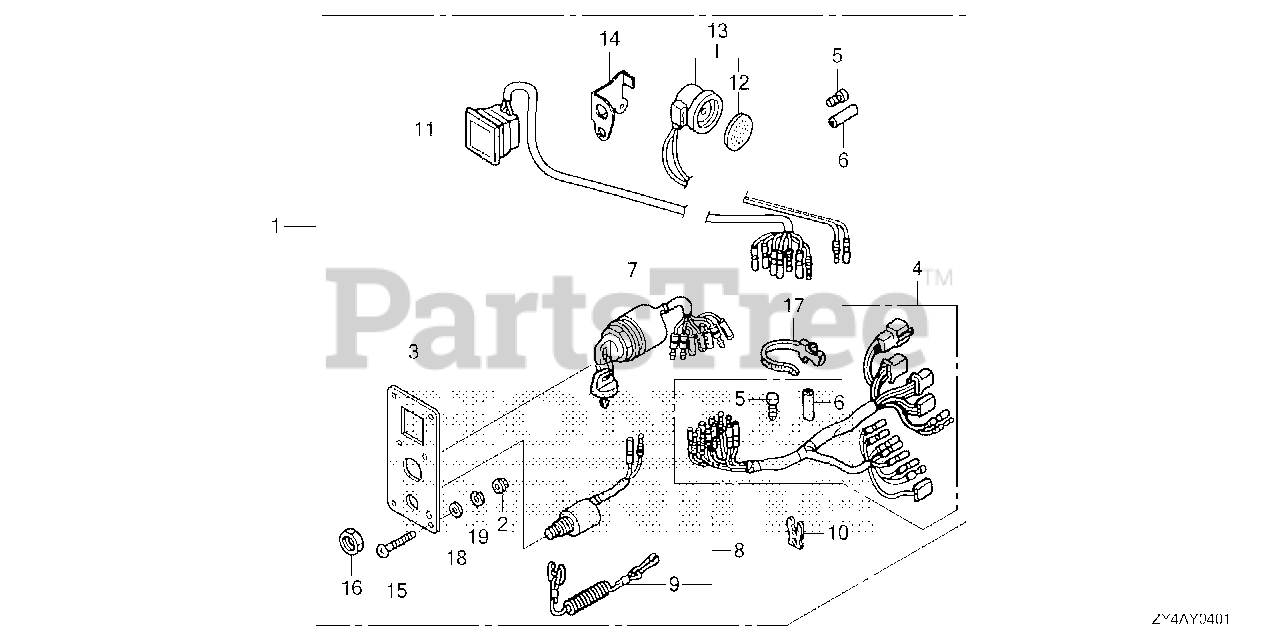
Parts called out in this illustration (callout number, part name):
1	PANEL KIT, SWITCH (4-LED)
2	NUT, FLANGE (5MM)
3	PANEL, CONTROL
4	HARNESS ASSY., SWITCH PANEL
5	PLUG, CONNECTOR (INNER)
6	PLUG, CONNECTOR (OUTER)
7	SWITCH ASSY., COMBINATION
8	SWITCH ASSY., EMERGENCY STOP
9	WIRE, EMERGENCY
10	CLIP, EMERGENCY LOCK
11	LAMP ASSY., INDICATION (4-LED)
12	PLATE, TURN SIGNAL BUZZER
13	BUZZER, WARNING
14	BRACKET, BUZZER
15	SCREW, PAN (5X40)
16	NUT, HEX. (16MM)
17	BAND, WIRE HARNESS (150MM) (NATURAL)
18	WASHER, PLAIN (5MM)
19	WASHER, SPRING (5MM)
